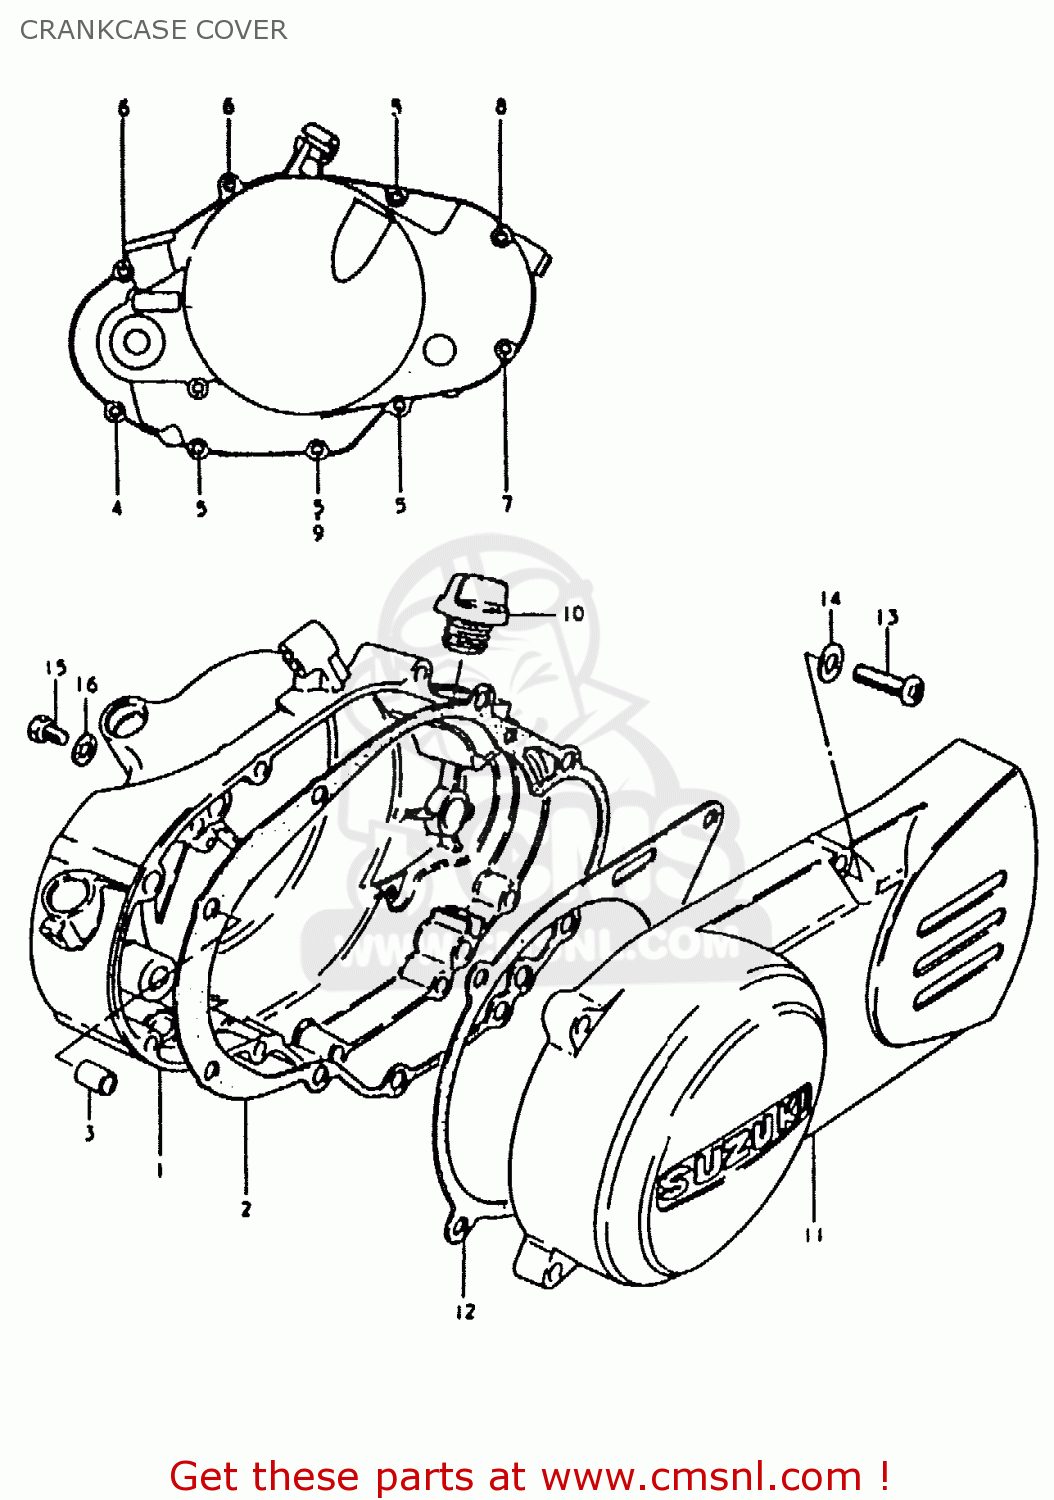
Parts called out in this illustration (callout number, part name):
1	COVER SET,CLUTCH
2	GASKET,CLUTCH COVER (MCA)
3	PIN
4	SCREW
5	SCREW 6X30
6	SCREW
7	SCREW
8	SCREW 6X60
9	GASKET(6.2X11X1).2 (NAS)
10	PLUG
11	COVER,MAGNETO
12	GASKET,MAGNETO COVER (NAS)
13	SCREW
14	WASHER 6MM
15	SCREW(6X10)
16	GASKET(6.2X11X1) (NAS)
